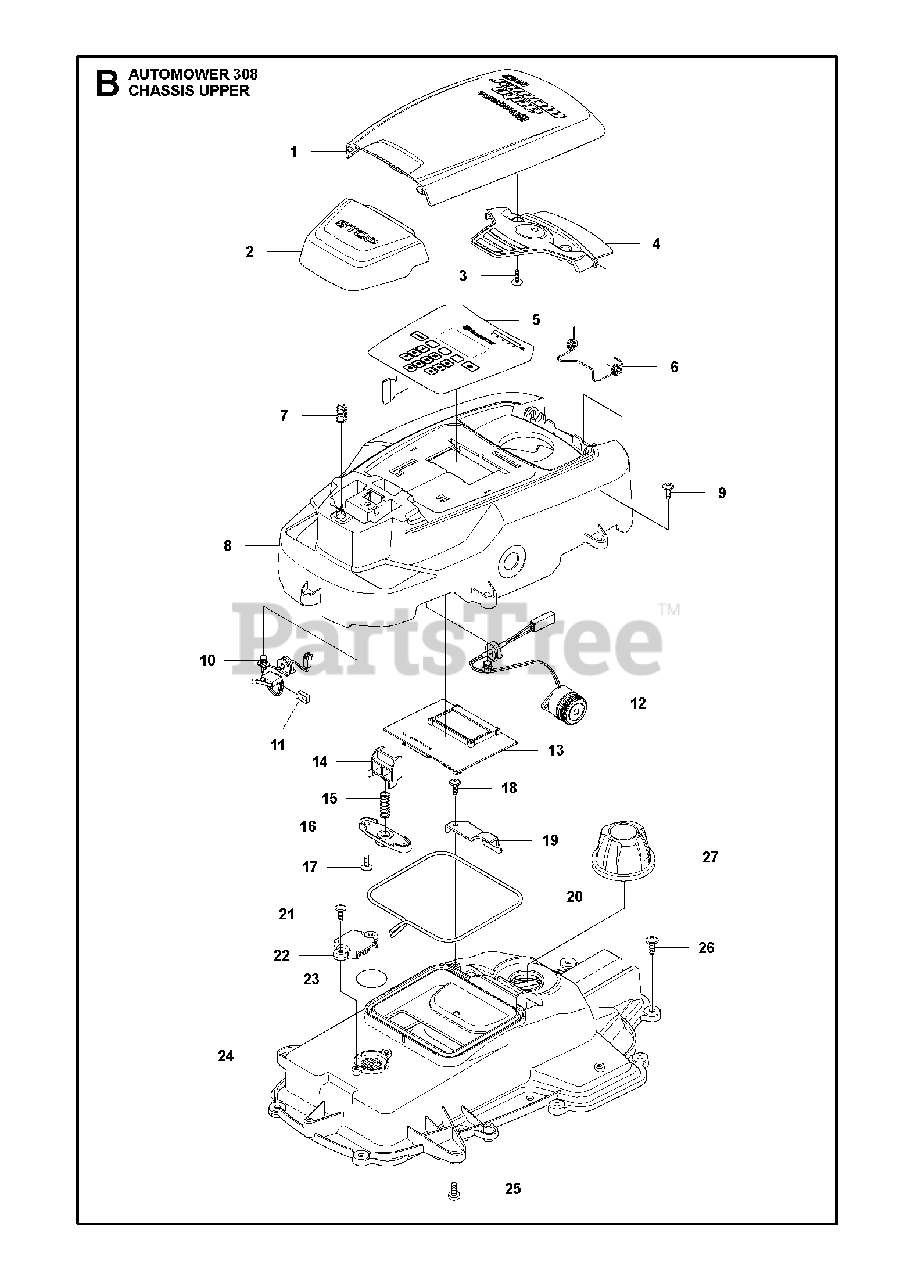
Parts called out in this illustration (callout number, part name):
3	SCREW 14MM
7	SPRING STOP BUTTON
9	SCREW 14MM
10	SWITCH STOP BUTTON
11	CLIP RETAINER
12	BUZZER DISPLAY COVER
14	LOCK STOP BUTTON
15	SPRING LOCK STOP BUTTON
16	SPRING HOLDER STOP BU
17	SCREW 14MM
18	SCREW 14MM
19	COVER HEIGHT INDICATO
20	SEALING STRIP P1
21	SCREW 14MM
22	Air Filter Cover
23	KIT AIR FILTER KIT 305 - 10 PC
25	SCREW ITXPANM M5X12 8
26	SCREW ITXPANT
